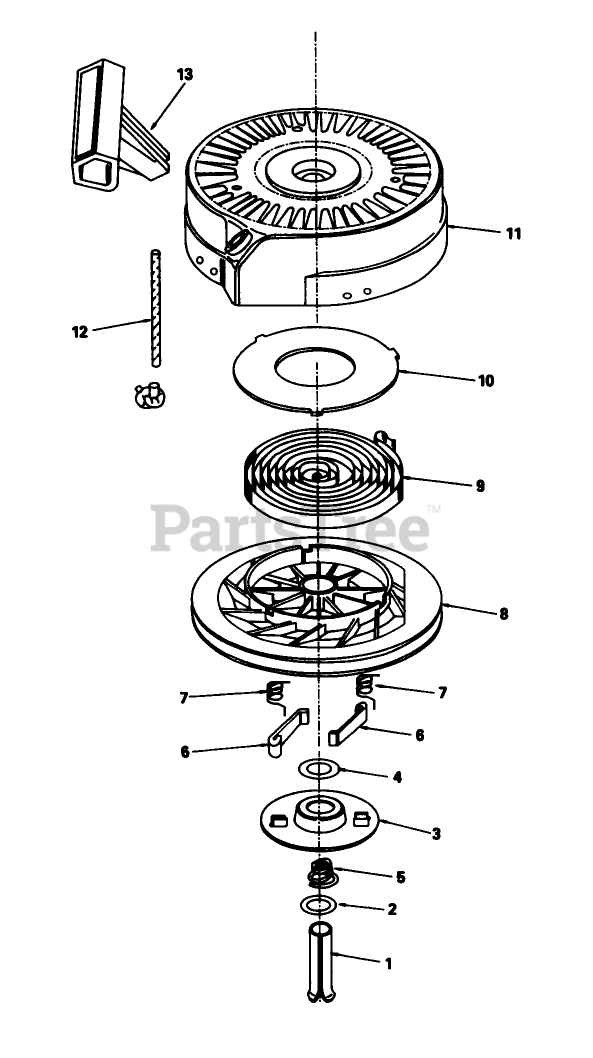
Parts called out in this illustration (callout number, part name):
1	Pin, Spring (Incl. Ref. #7)
2	Washer
3	Retainer
4	Washer
5	Brake Spring
6	Dog-Starter
7	Spring-Dog
8	Pulley
9	Rewind Spring
10	Cover-Spring
11	Housing-Starter
12	Rope-Starter (98 cut to length)
13	Handle-Starter
